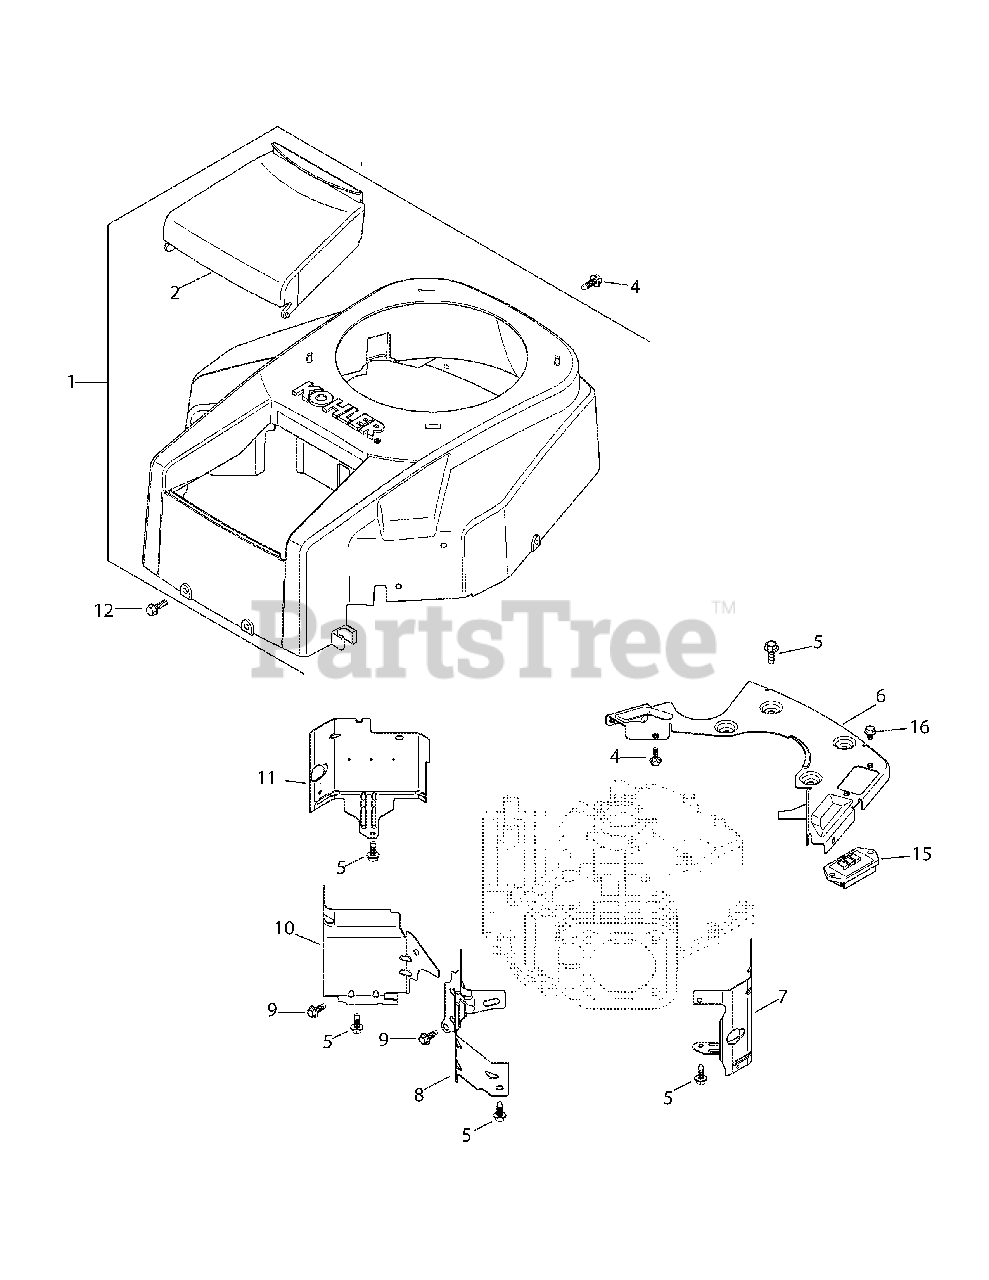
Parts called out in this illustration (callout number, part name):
1	Housing Blower Kit (Inc. 2 & KH-41-037-10-S)
2	Air Cleaner Cover
4	Flg. Thd. Frm. Screw, M5 X 0.8 X 16
5	Flg. Thd. Frm. Screw, M6 X 1.0 X 16
6	Backing Plate Kit
7	Cyl. Barrel Baffle - #2 Side
8	Valley Baffle - #2 Side
9	Flg. Thd. Frm. Screw, M5 X .8 X 10
10	Valley Baffle - #1 Side
11	Cyl. Barrel Baffle - #1 Side
12	Tap Screw, M6 X 1.7 X 18
15	Regulator/Rectifier
16	Flg. Thd. Frm. Screw, M6 X 1.0 X 10
